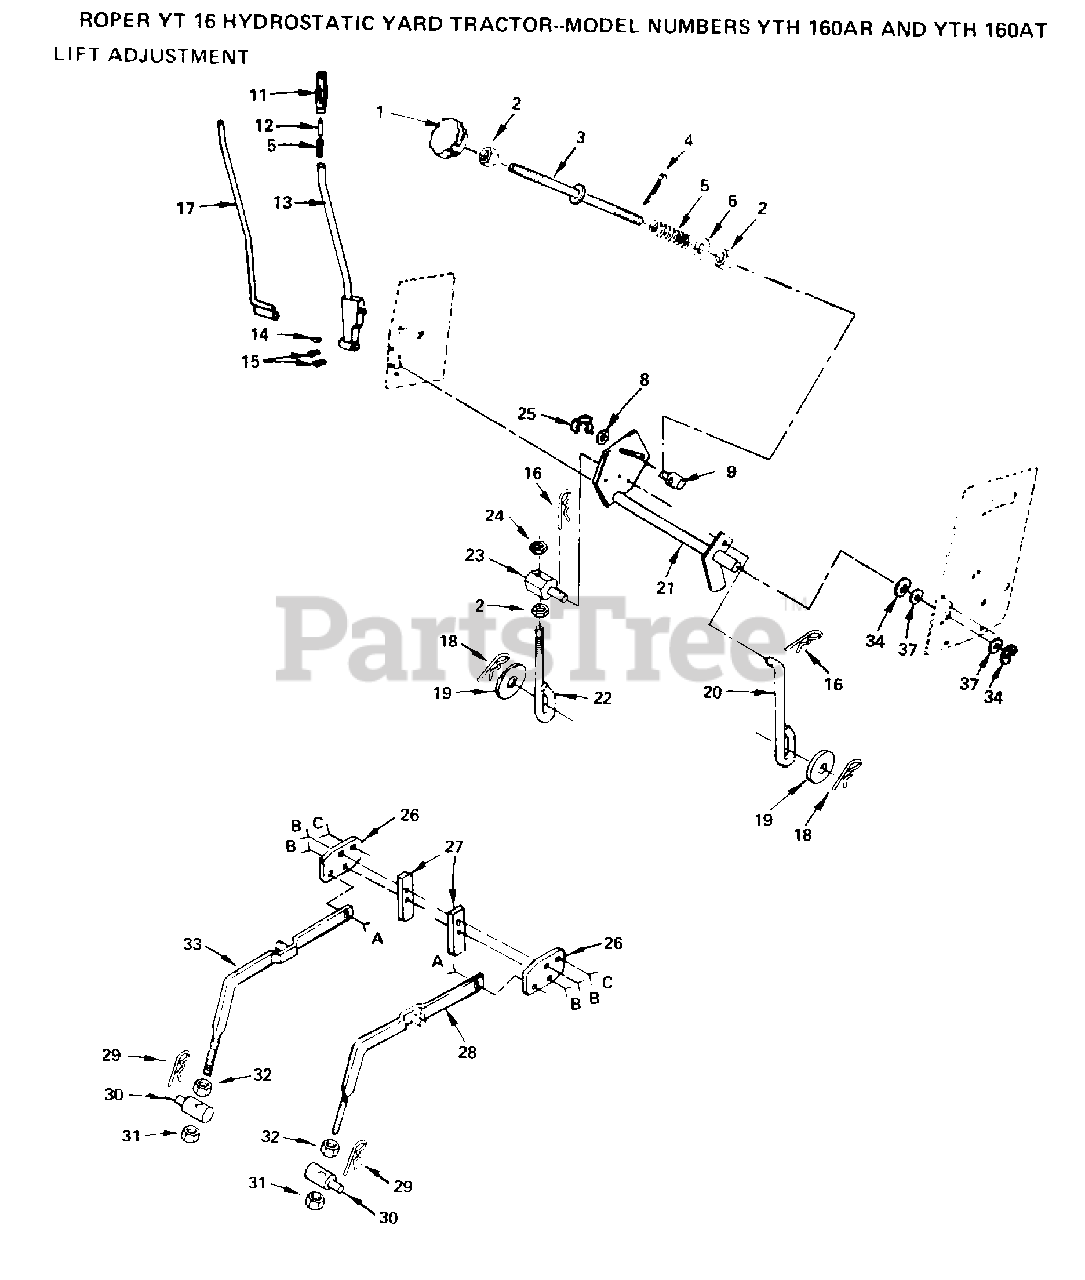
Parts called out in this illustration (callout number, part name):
2	NUT
3	ROD ADJUST LT
5	SPRING T
6	WASHER
8	WASHER
9	TRUNION T
13	LEVER ASSY LT
17	ROD ASSY-LEVER LT
18	SPRING.RETAINER
22	LINK LIFT LT
25	KLIP RING
26	"BRACKET, SUSPE T"
29	SPRING H
31	NUT LTV
32	NUT
34	RING
37	WASHER
